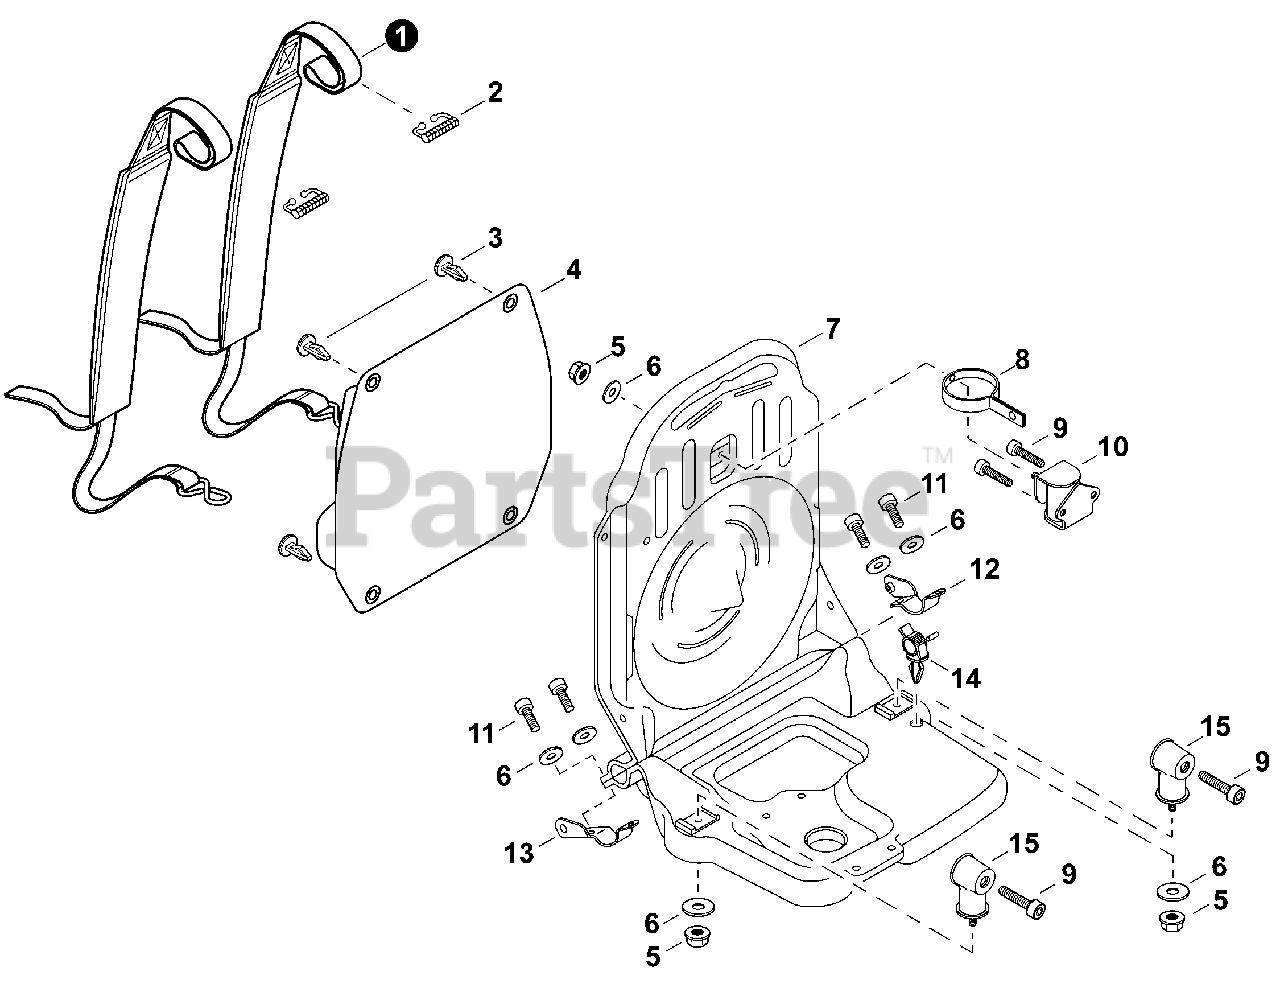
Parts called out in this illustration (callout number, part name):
1	HARNESS, BACKPACK
2	CLIP, HARNESS
4	CUSHION, BACKPACK
5	NUT, FLANGE M5
6	WASHER 5.5×16×2T
7	FRAME, BACKPACK
8	RETAINER
9	SCREW TAPPING 5×16
11	BOLT 5×20
12	CONNECTOR, HARNESS (B)
13	CONNECTOR, HARNESS (A)
14	CLIP, CABLE
15	CUSHION, FRAME 5
